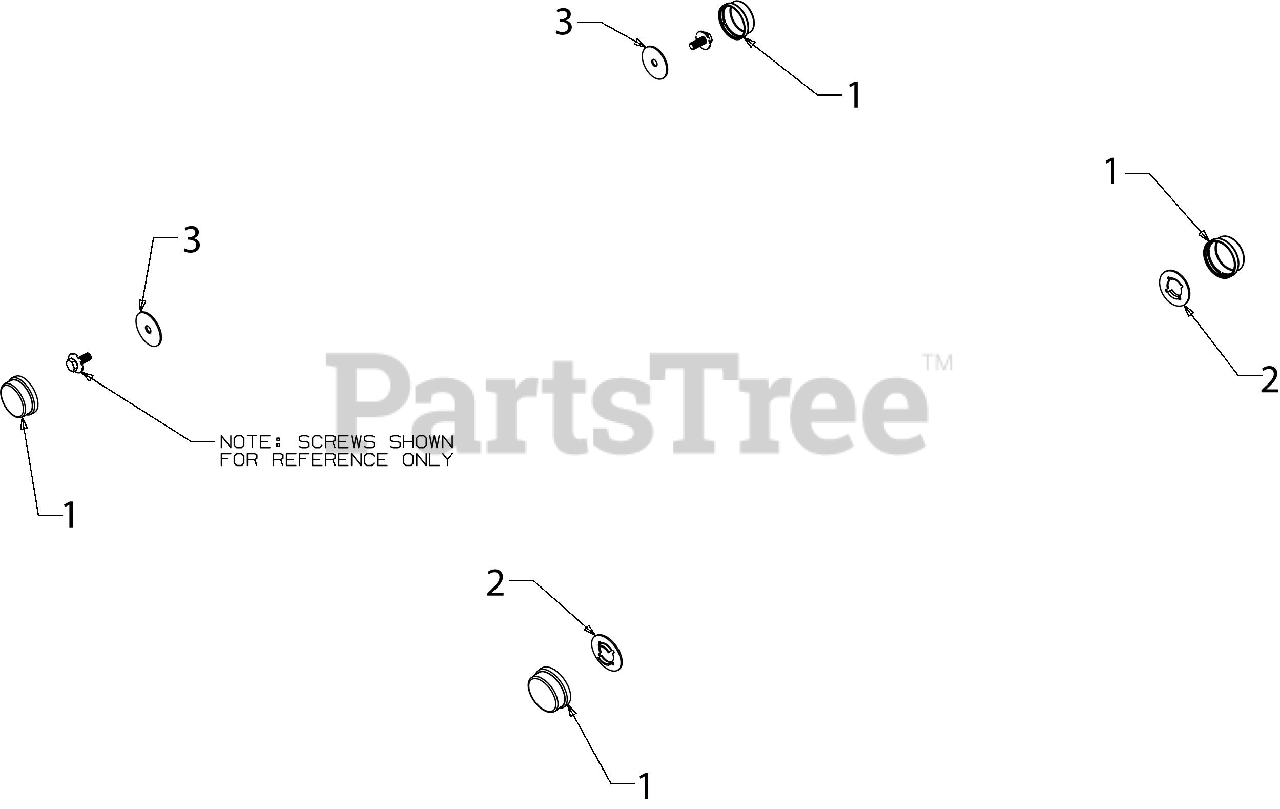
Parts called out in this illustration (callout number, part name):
1	HUB CAP-BLACK
2	FLAT WASHER .781 ID x1.590 OD
3	FLAT WASHER .350X1.59X.062
